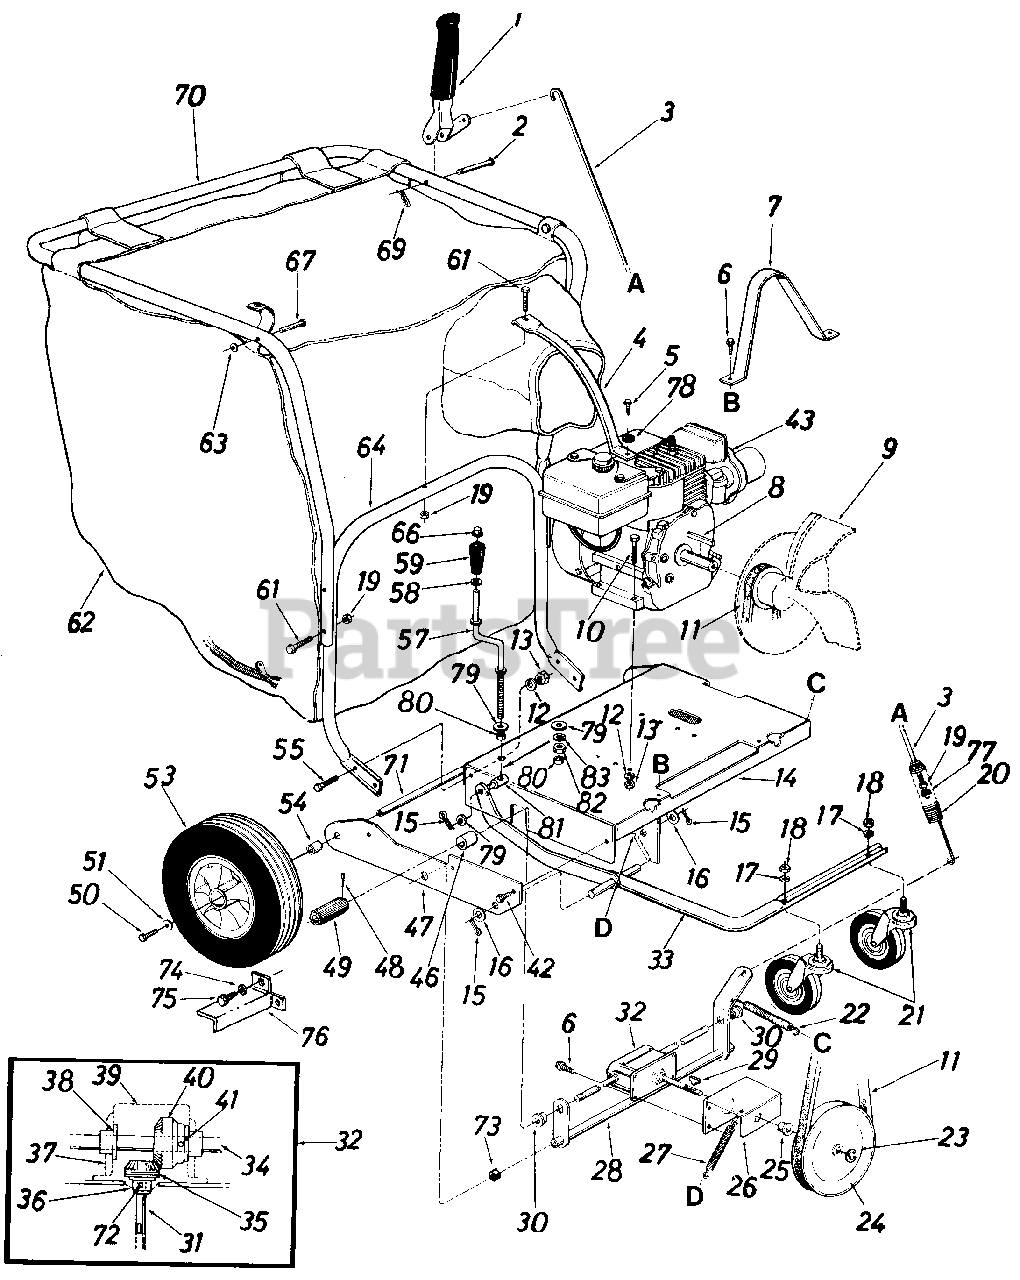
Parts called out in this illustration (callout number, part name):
1	Clutch Grip Ass'y.
2	Clevis Pin .375" Dia. x 1.88"
3	Clutch Rod 32" Lg.
4	Handle Brace (Painted)
5	Part of Engine
6	Hex L.-Wash. Hd. B 0 Tap Scr. 1/4" x .62" 4.
11	"V"-Belt
12	L.-Wash. 5/16" I.D.
13	Hex Nut 5/16-18 Thd.
16	Fl.-Wash. .63" I.D. x 1.25" O.D.
17	L.-Wash. 1/2" I.D.
18	Hex Nut 1/2-13 Thd.
19	Hex Cent. L.-Nut 1/4-20 Thd.
20	Extension Spring .78" O.D. x.75" Lg.
21	Swivel Caster Wheel 5" Dia. x 1.25"
22	Extension Spring .38" O.D. x 7.50" Lg.
23	Snap "E"-Ring .50" Dia. Shaft
24	"V"-Pulley 5/8" x 6.50" O.D.
25	Flange Bearing .502" I.D.
28	Clutch Bracket Ass'y.
29	2 Woodruff Key 3/32" Dia. x .81" Lg.
30	Hex Flange Bearing Bronze .625" I.D.
31	Pinion Shaft .50" Dia. x5.0"
32	Gear Box Ass'y. Comp.
35	Bevel Gear .50" I.D. x 14 Teeth
36	Flange Bearing .503" I.D.
37	Gear Box
38	Flange Bearing .630" I.D.
39	Gear Box Cover
40	Bevel Gear .62" I.D. x 28 Teeth
41	Spring Pin Spiral 3/16" Dia. x 1.25" Lg.
42	Hex Wash. Hd. "AB" Tap Scr. 5/16" x .75" Lg.
43	Engine
46	Spacer .63 I.D. x .88" O.D. x .56" L.g t
49	Drive Pinion
50	Hex Locking Bolt 5/16-24 x .62" Lg.
51	Fl.-Wash. .34" I.D. x .87" O.D.
53	Wheel Ass'y.-Comp. 12" x 3"
54	Spacer .63" I.D. x 1.0" O.D. x .94" Lg.
55	Hex Bolt 5/16-18 x .75" Lg.
57	Height Adjustment Crank
58	Fl.-Wash. .385" I.D. x .62" 0.
59	Crank Knob
61	Hex Bolt 1/4-20 x 1.75" Lg.
62	Vacuum Bag-Felt
63	Push Speed Nut .25" Dia. Stud
66	Push Nut 3/8" Dia.
67	Stud Pin .250" Dia. x 1.75"
69	Internal Cotter Pin 3/8" Dia.
70	Upper Handle Painted
71	Rear Axle .624" Dia. x 24.37"
72	Spring Roll Pin 5/32" Dia. x 1.12
73	Spacer .82" I.D. x 1.0" O.D. x .305 Lg.
74	L.-Wash. .265" I.D.
75	Hex Self Tap Scr. 1/4" x 3/8" Lg.
78	Belleville Washer
79	Fl.-Wash. .35" I.D. x .87" O.D.
80	Spacer .38" I.D. x .50" O.D. x .1 80" L.g
81	Ferrule 3/8-8 x .38" Dia.
82	Hex Nut 3/8-8 Thd.
83	L.-Wash. 3/8" I.D.
